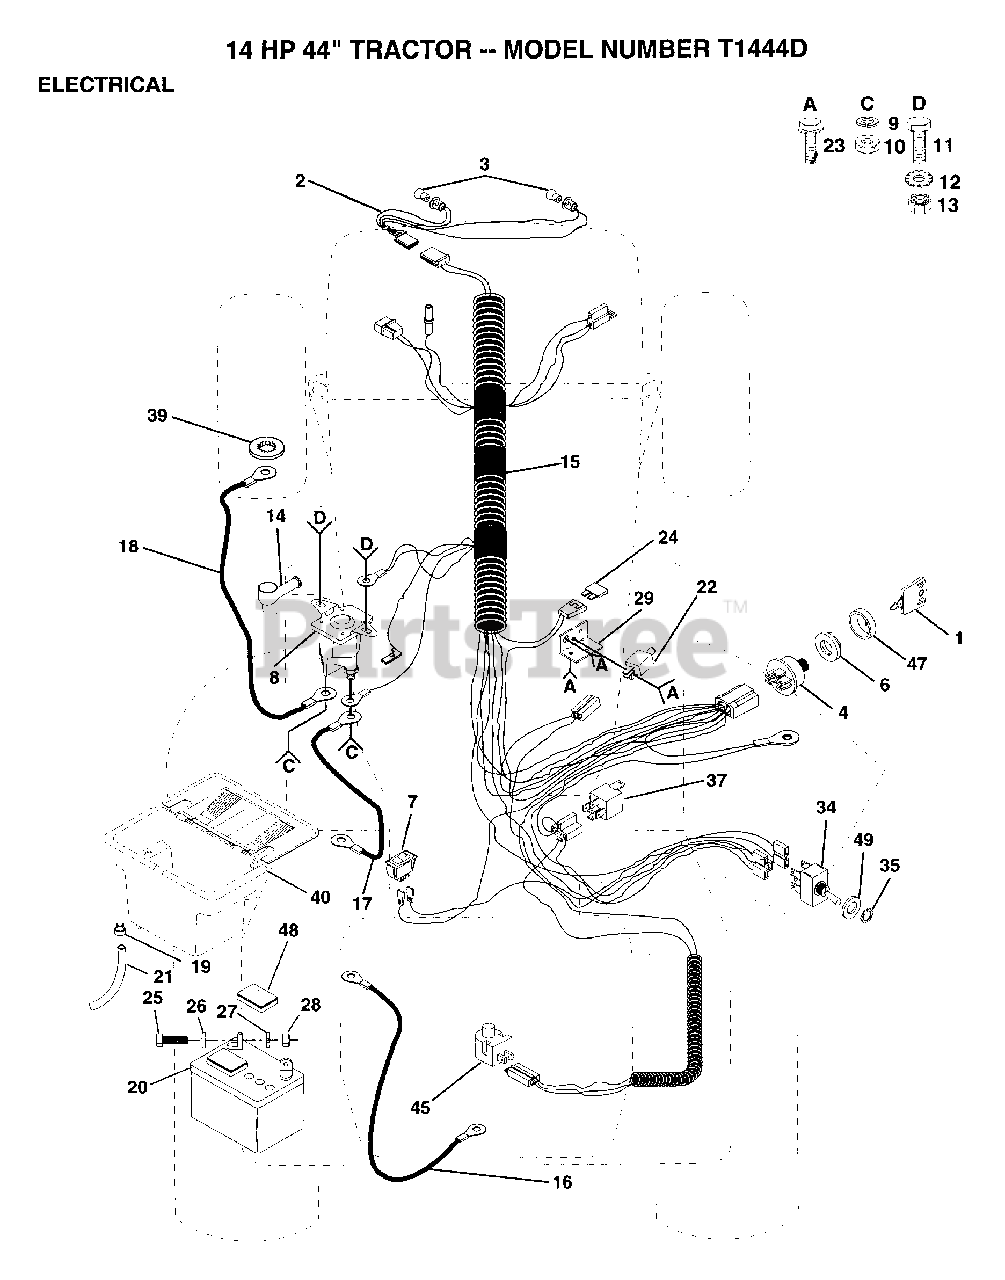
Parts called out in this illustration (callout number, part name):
1	KEY
2	"HARNESS,LIGHT SOC"
3	HEADLAMP BULB
6	NUT IGNITION
7	SWITCH LT
10	NUT
11	BOLT
13	NUT
15	HARNESS.IGN
16	CABLE T
18	"CABLE T, BATTERY"
19	HOSE CLAMP T
21	TUBE T
22	SWITCH-INTER. GT
23	SCREW
24	FUSE HYT
25	BOLT LT
26	WASHER
27	LOCKWASHER
29	BRACKET LT
34	"SWITCH,PTO"
35	HEX NUT T
37	RELAY ASSY T
39	LOCKWASHER
45	SWITCH SEAT
48	"CAP,BATTERY "
49	WASHER
